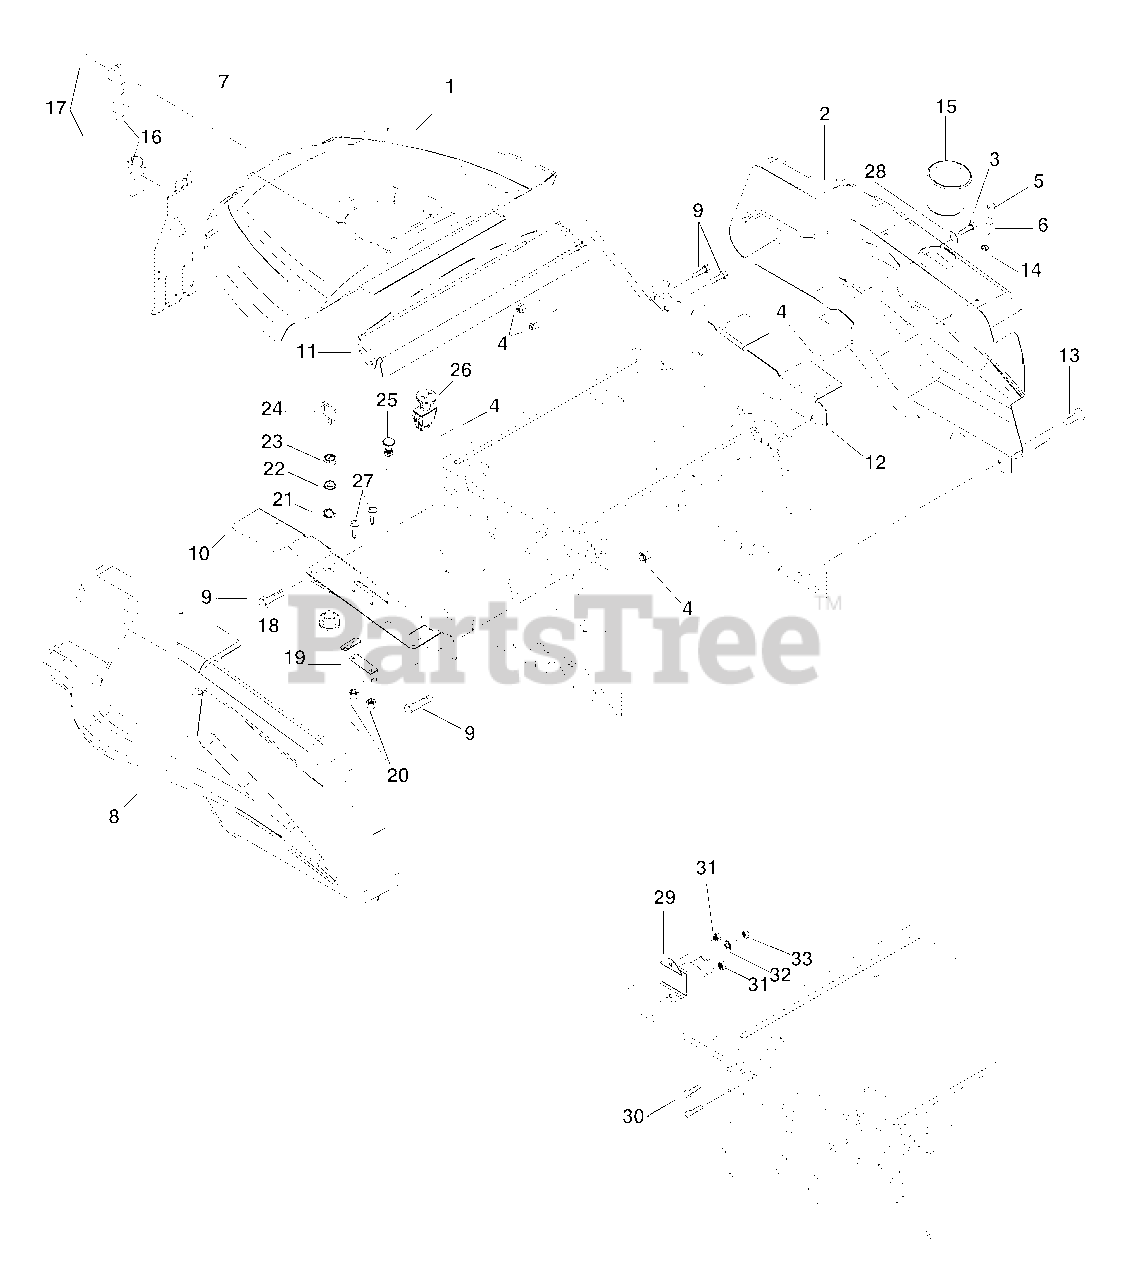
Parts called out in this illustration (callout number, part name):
1	Shroud, Top
2	Shroud, Side Left Hand
3	Bolt-Hex .31-18 x .75 Grade 5
4	Nut-Locking-Nylon .312-18
5	Snap-Cap Top Cap
6	Screw-Tapping 10-24 x .50
7	Rivet-Burr .125 x .505 x.048
8	Shroud-Side Right Hand
9	Bolt-Hex .312-18 x .75 Grade 5
10	Bracket-Control
11	Bracket-Hood
12	Bracket-Fuel Tank
13	Screw-Tapping .312-18 x .75 Hex Washer Head
14	Snap-Cap Washer
15	Cupholder
16	Latch, Flexible
17	Rivet-Pop .125 x .357 Dome
18	Key Switch
19	Cable-Throttle
20	Nut-Locking-Nylon 10-24
21	Washer-Lock-Internal .563 x .040
22	Nut-Panel .562-24
23	Cap-Ignition Switch
24	Key with Cap
24	Key Chain
25	Cable-Choke
25	Plug-Hole Plastic .44
26	Switch-Clutch
27	Screw-Machine 10-24 x .50
28	Washer-Flat-Steel .344 x .688 x .065
29	Solenoid
30	Bolt-Hex .25-20 x .50
31	Nut-Locking-Center .25-20 Grade 2
32	Washer-Lock-Internal .31
33	Nut-Jam .312-24
